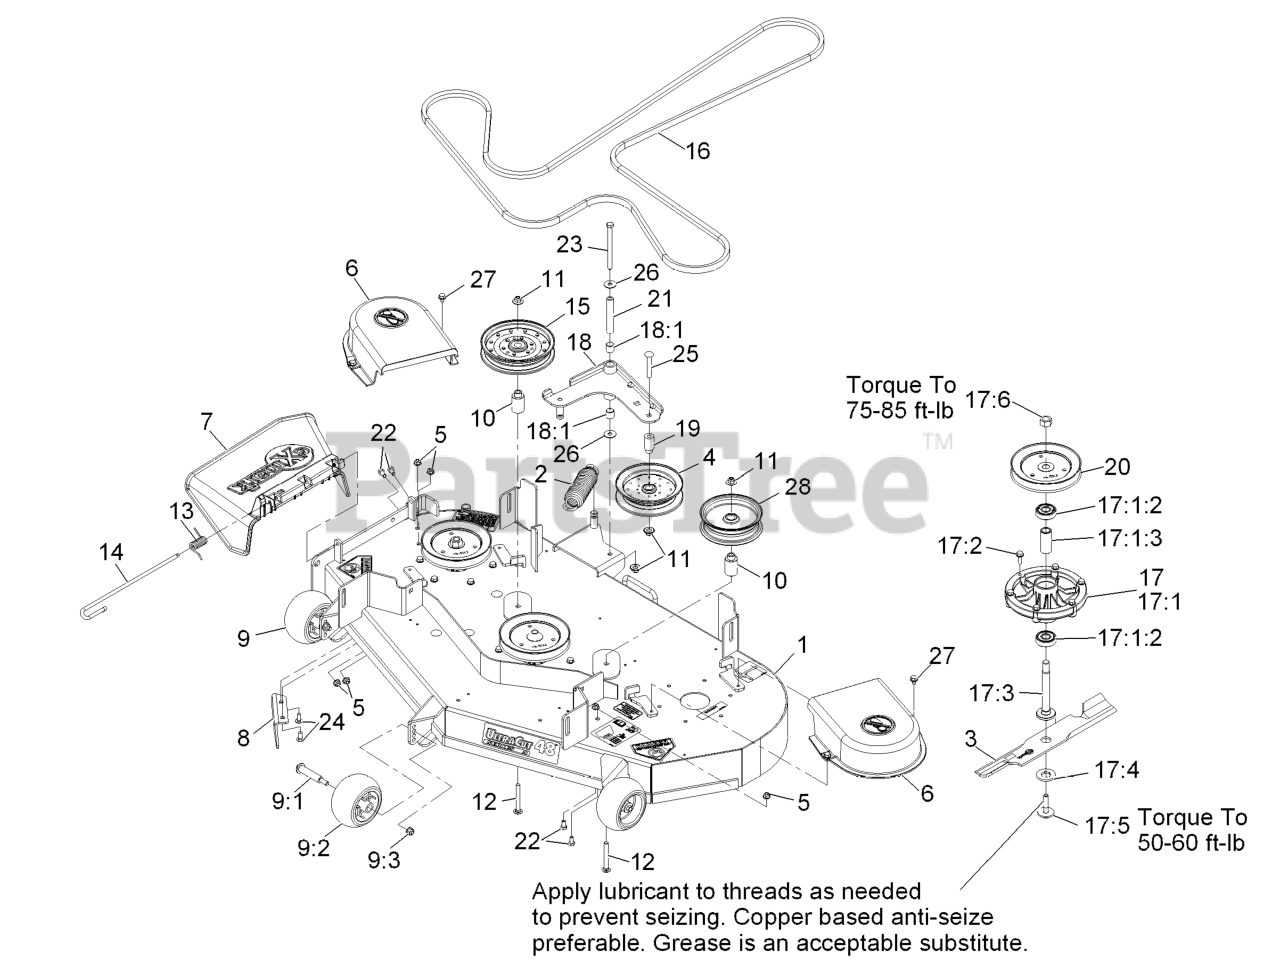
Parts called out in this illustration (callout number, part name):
1	ASM-482 DECK W/DECALS
5	NUT-HF, NI
6	SHIELD-BELT
7	CHUTE DEFLECTOR XRK M056
8	BAFFLE-DISCHARGE
9	ANTI-SCALP ROLLER KIT
9:1	BOLT-SHOULDER
9:2	ROLLER-SCALP, ANTI
9:3	NUT-HF, NI
10	BUSHING-IDLER
11	Nut-Nyloc 3/8-16 Flg
12	BOLT-CARRIAGE
13	SPRING-TORSION
14	PIN-CHUTE
16	BELT-B154.88
17	CUTTER HOUSING ASM
17:1	HOUSING-CUTTER
17:1:2	BEARING
17:1:3	SPACER-BEARING
17:2	SCREW-TAPTITE
17:3	SPINDLE-HEX PILOT
17:4	WASHER-BLADE DRIVE
17:5	BOLT-BLADE, SEM
17:6	NUT-HEX
18:1	SLEEVE-BEARING
19	BUSHING-IDLER
20	SHEAVE,BLADE DRIVE 5.90
21	BUSHING
22	SCREW-HH
23	SCREW-HH
24	SCREW-CARR
25	SCREW-CARR
